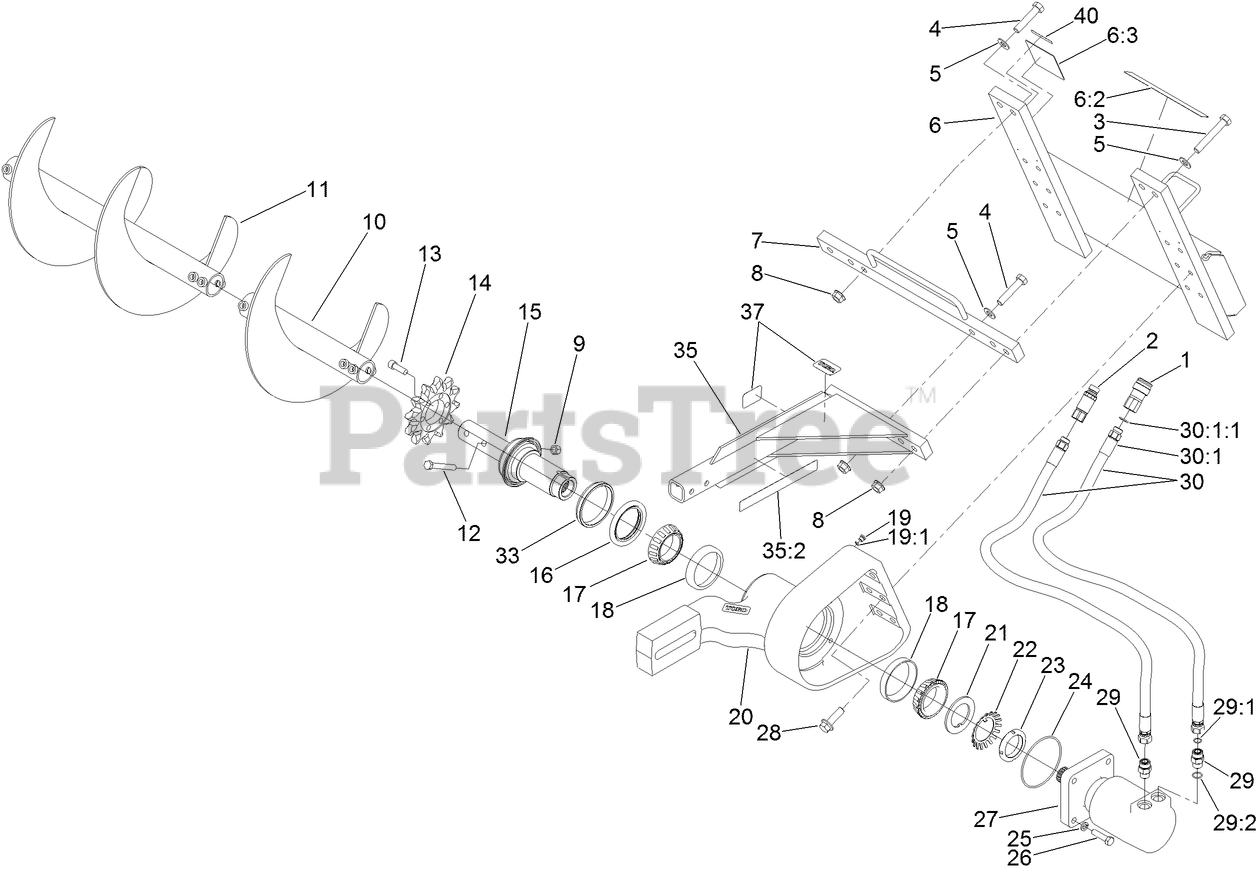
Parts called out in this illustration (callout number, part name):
1	COUPLER-FACE, FLUSH
2	NIPPLE-CONNECT, PRESSURE
3	SCREW-HH
4	SCREW-HH
5	WASHER-FLAT
6	MOUNT ASM
6:2	DECAL-DANGER
6:3	DECAL-DANGER
7	CROSSBAR ASM
8	NUT-FLANGE
9	NUT-LOCK, NI
10	AUGER ASM
11	AUGER ASM
12	SCREW-HH
13	SCREW-HSH
14	SPROCKET-TRENCHER
15	SHAFT-TRENCHER
16	SEAL-SHAFT
17	CONE-BEARING
18	CUP-BEARING
19	PLUG ASM
19:1	O-RING
20	MOUNT-BOOM
21	WASHER-TONGUED
22	WASHER-LOCK, BEARING
23	NUT-LOCK, BEARING
24	O-RING
25	SCREW-HH
26	SCREW-HH
27	MOTOR-HYD, HIGH TORQUE
29	FITTING-STRAIGHT
29:1	O-RING
29:2	O-RING
30	HOSE ASM
30:1	FITTING-STRAIGHT
30:1:1	O-RING
33	SPACER
35	SAFETY RAIL ASM
35:2	DECAL-DANGER
37	DECAL
40	DECAL-WARNING
